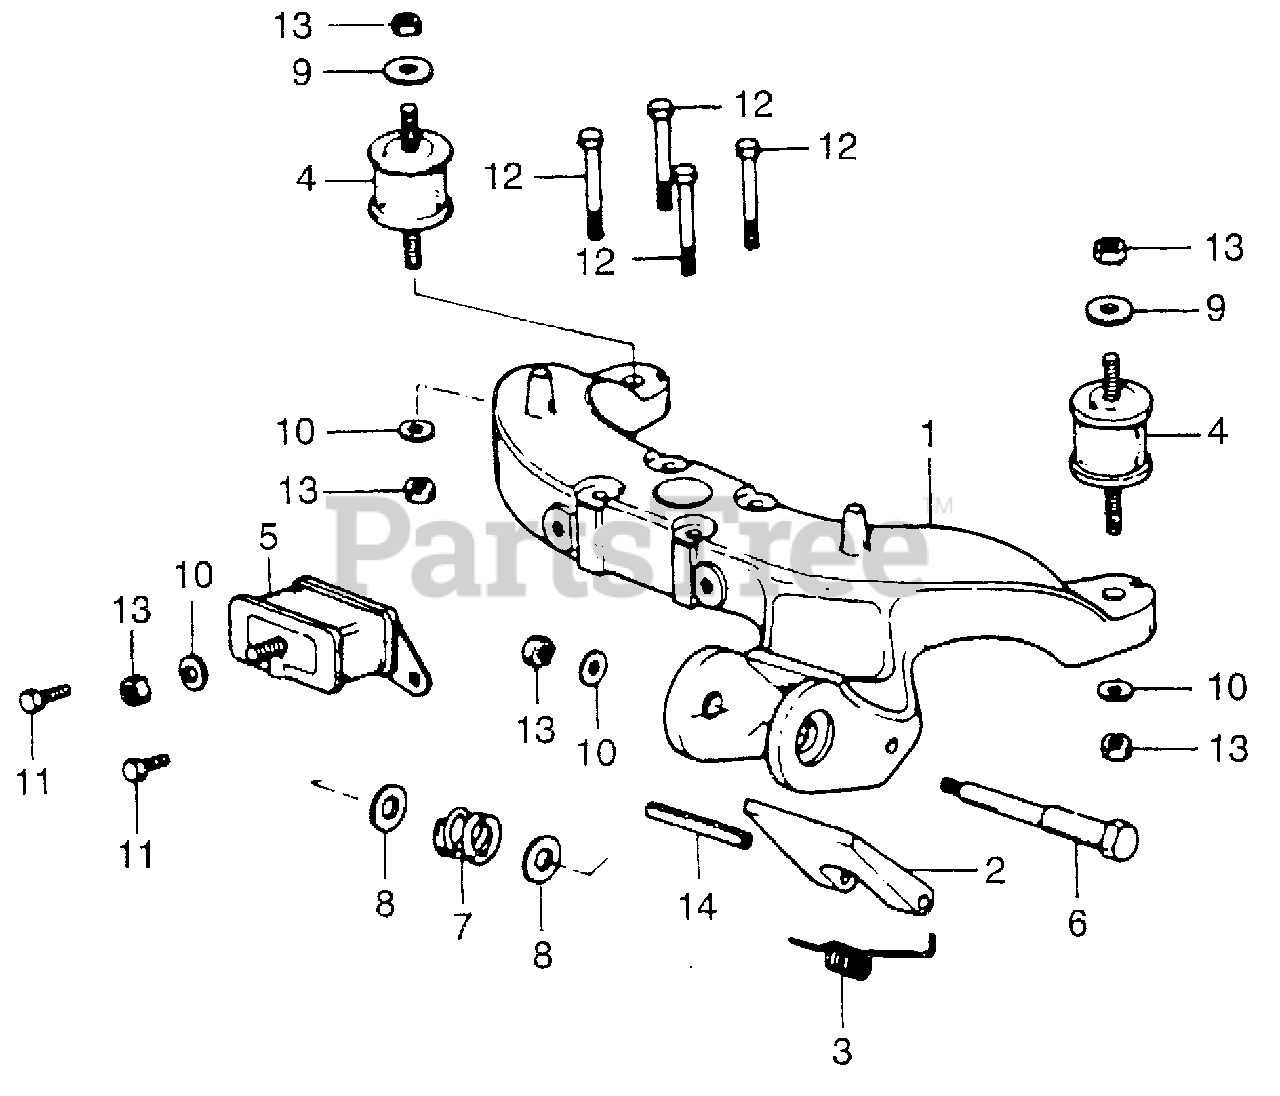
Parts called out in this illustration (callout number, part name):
1	FRAME, SETTING *B9* (ATLANTIS BLUE) (NOT AVAILABLE)
2	STOPPER, HANDLE *B9* (ATLANTIS BLUE)
3	SPRING, HANDLE
4	RUBBER, SETTING (UPPER)
5	RUBBER, THRUST SETTING
6	SCREW, HANDLE PIVOT
7	SPRING, HANDLE PIVOT
8	WASHER, PLAIN (10MM)
9	WASHER (8MM)
10	WASHER, PLAIN (8MM)
11	BOLT, HEX. (6X14)
12	BOLT, HEX. (6X40)
13	NUT, HEX. (8MM)
14	PIN, SPRING (6X50)
